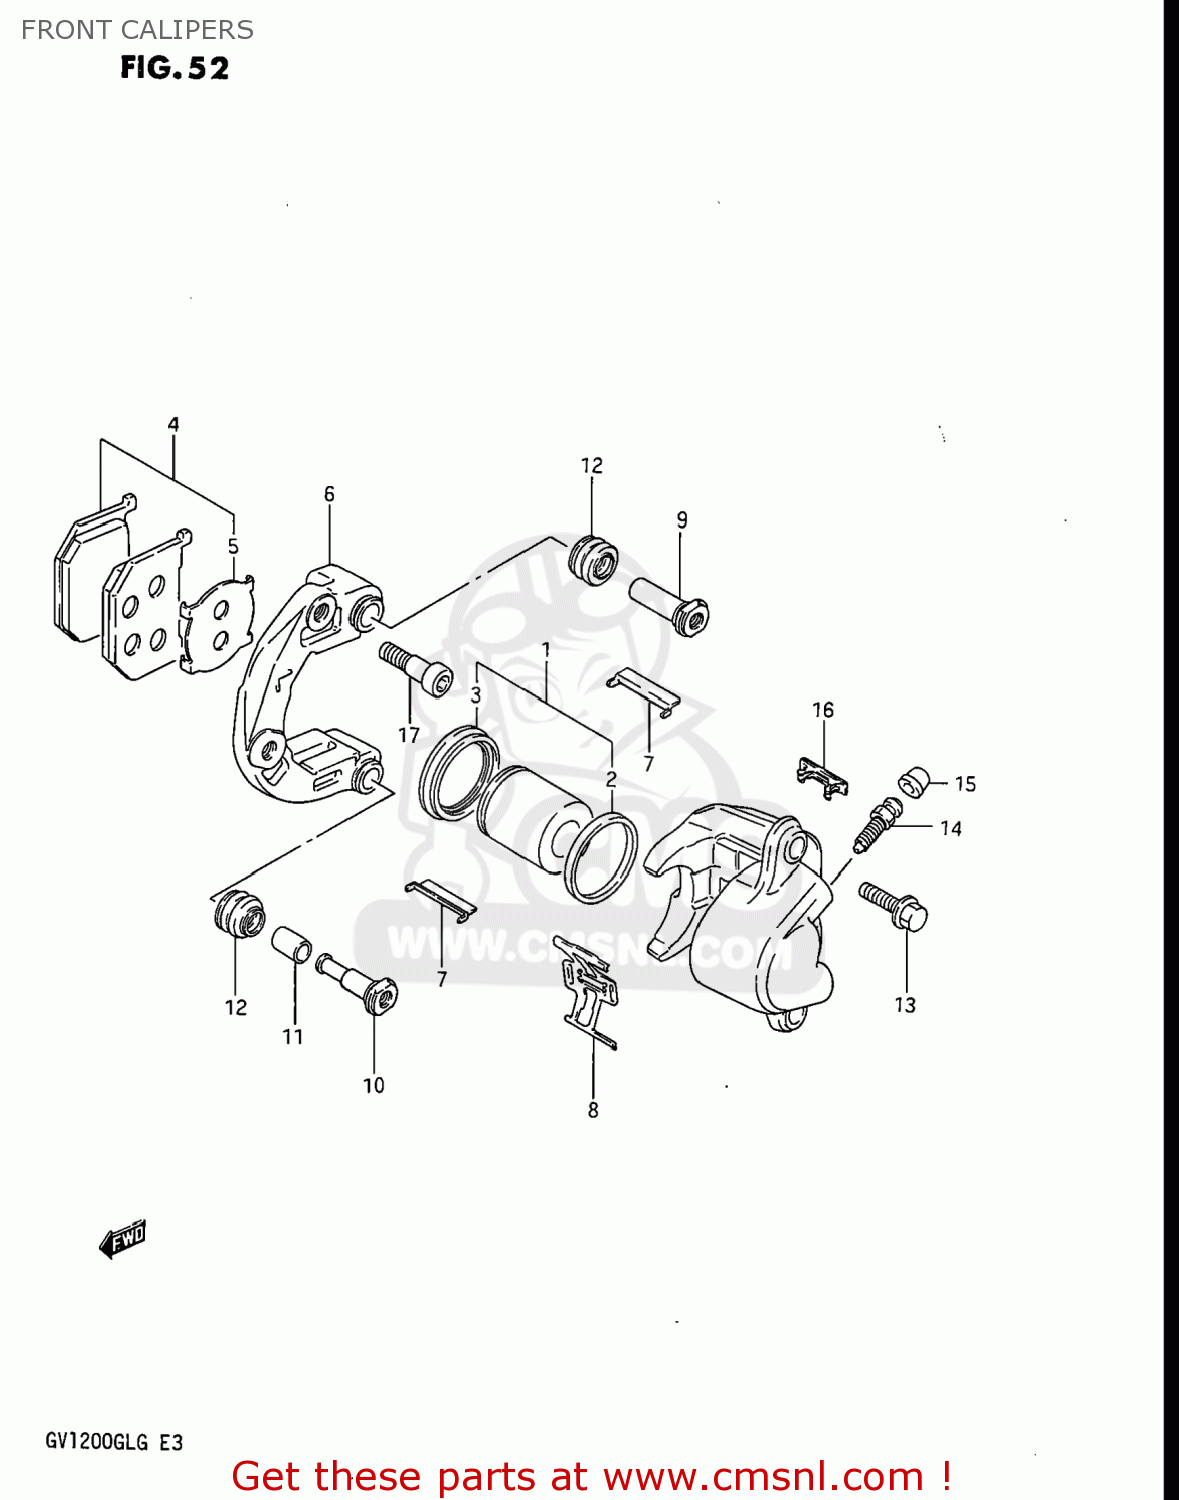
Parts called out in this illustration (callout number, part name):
1	PISTON SET
2	SEAL,PISTON
3	BOOT,PISTON
4	PAD SET
5	SHIM,PAD
6	COVER,CALIPER
7	GUIDE,PAD
8	SPRING,PAD
9	AXLE NO.1
10	AXLE NO.2
11	BUSH,AXLE
12	BOOT,AXLE
13	BOLT
14	BLEEDER
15	CAP,BREATHER
16	COVER
17	BOLT
